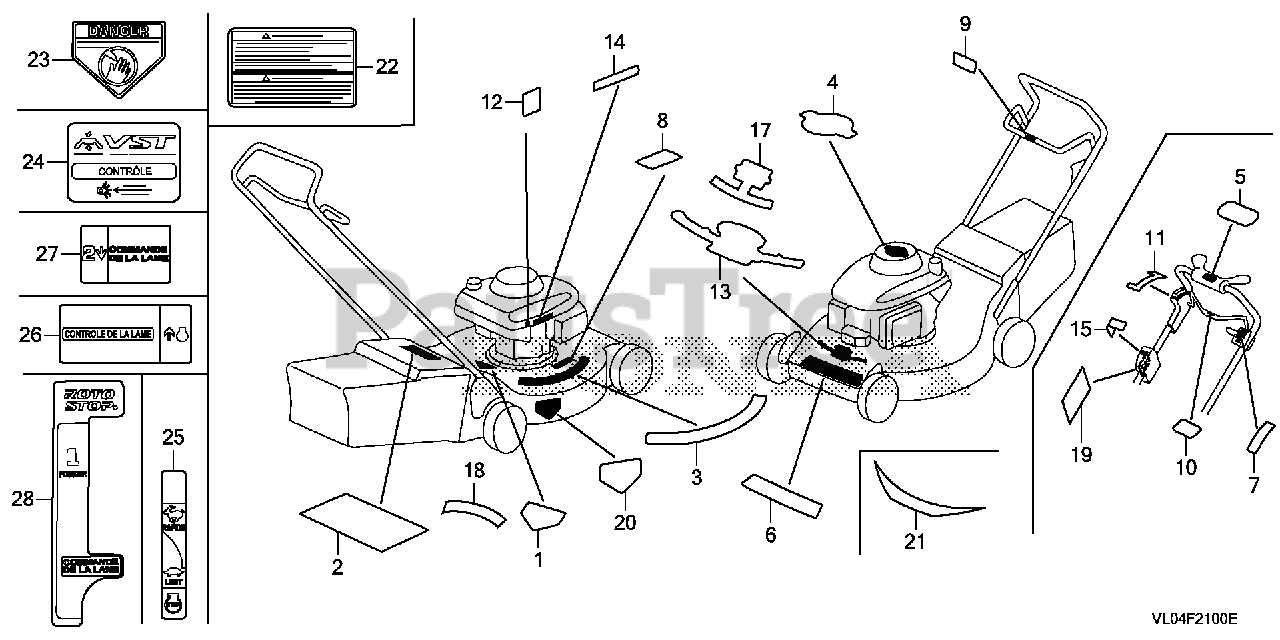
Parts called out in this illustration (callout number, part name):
2	LABEL, WARNING (ENGLISH)
5	MARK, CLUTCH INDICATION (ENGLISH)
6	MARK, HONDA
8	LABEL, HEAT WARNING
10	MARK, BLADE CONTROL (ENGLISH)
15	MARK, ENGINE SWITCH
17	MARK, SALES POINT (TWIN BLADE)
18	MARK, CLIP DIRECTOR
19	MARK, ELECTRIC STARTER
20	CAUTION C, HOUSING
